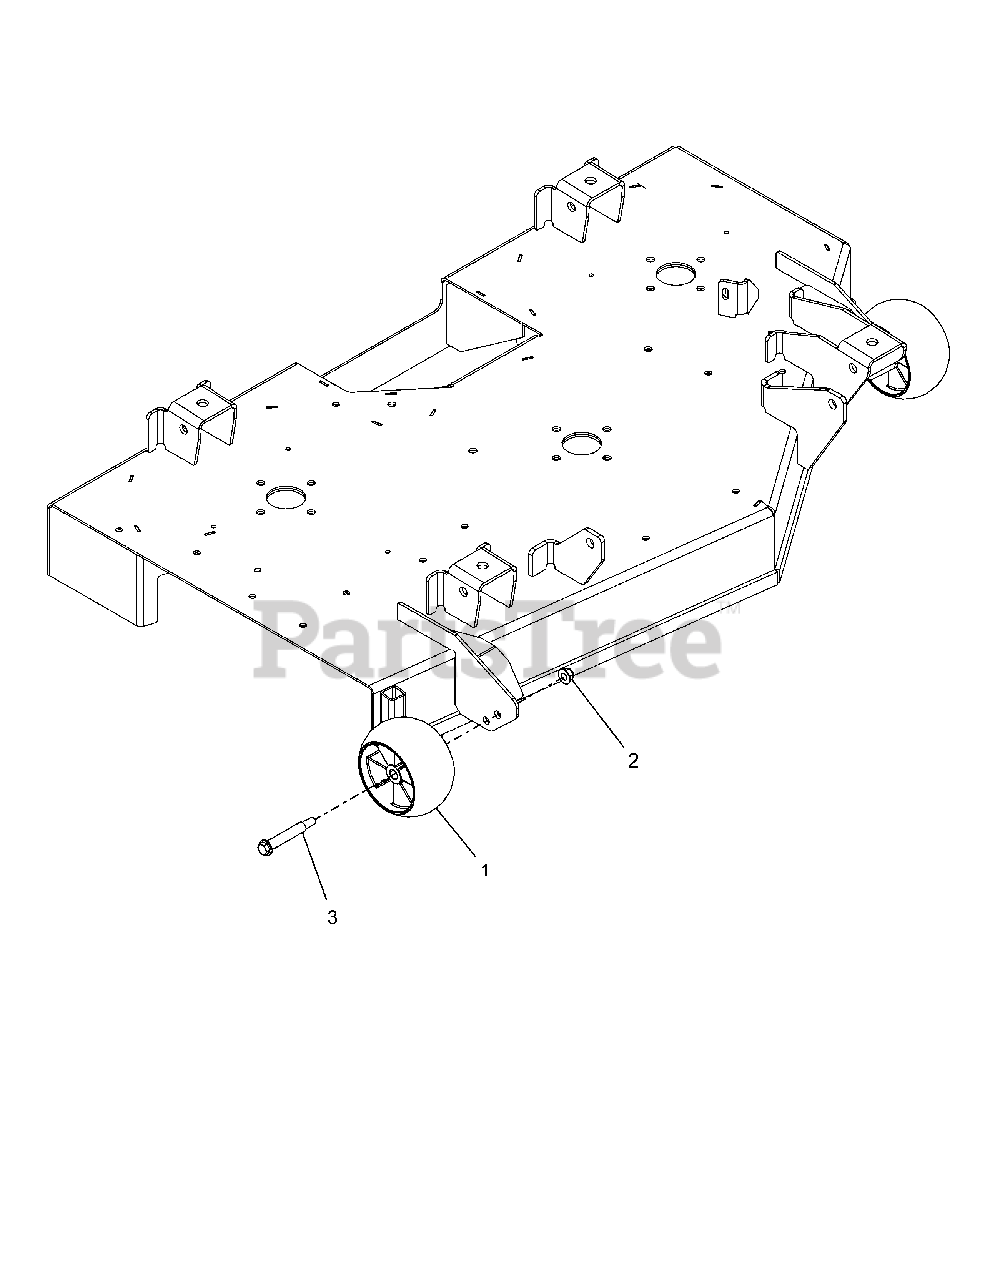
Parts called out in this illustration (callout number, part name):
1	ANTI-SCALP WHEEL - 5X OS
2	NUT,NYL-FLG .38-16 GF ZCC
3	BLT-SHLDR .38-16X2.50 HWH G5
